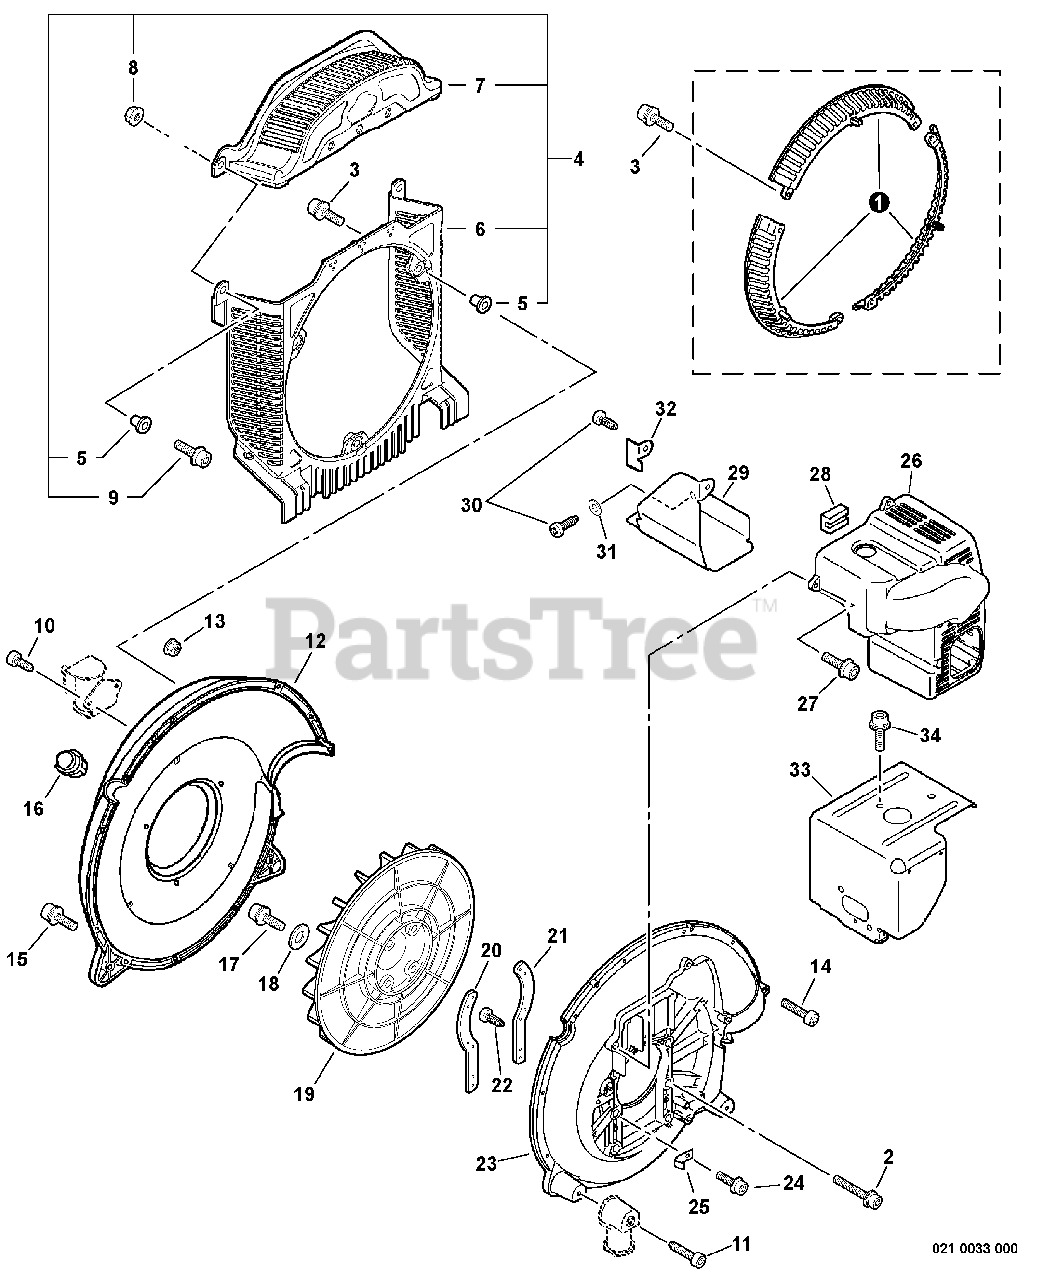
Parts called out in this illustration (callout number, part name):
1	GUARD, DEBRIS
2	SCREW 6×35
3	SCREW TAPPING 5×20
4	GUARD KIT, DEBRIS
6	SHIELD, DEBRIS - LOWER
7	SHIELD, DEBRIS - UPPER
8	NUT, LOCK M5
9	BOLT 5×20
10	SCREW TAPPING 5×16
11	SCREW TAPPING 5×16
12	COVER, FAN - INNER
13	NUT, FLANGE M5
14	BOLT 5×60
15	SCREW TAPPING 5×20
16	PLUG, FAN CASE
17	BOLT 6×35
19	FAN, BLOWER
20	PLATE, ENGINE
21	PLATE, ENGINE
22	SCREW 5×14
23	COVER, FAN - OUTER
24	SCREW TAPPING 5×16
26	COVER, ENGINE
27	SCREW TAPPING 5×20
28	CUSHION
29	INSULATOR, MUFFLER
30	SCREW 5×10
31	WASHER 5.5×12×0.8
32	PLATE, ANGLE
33	COVER, CYLINDER
34	BOLT 5×8
